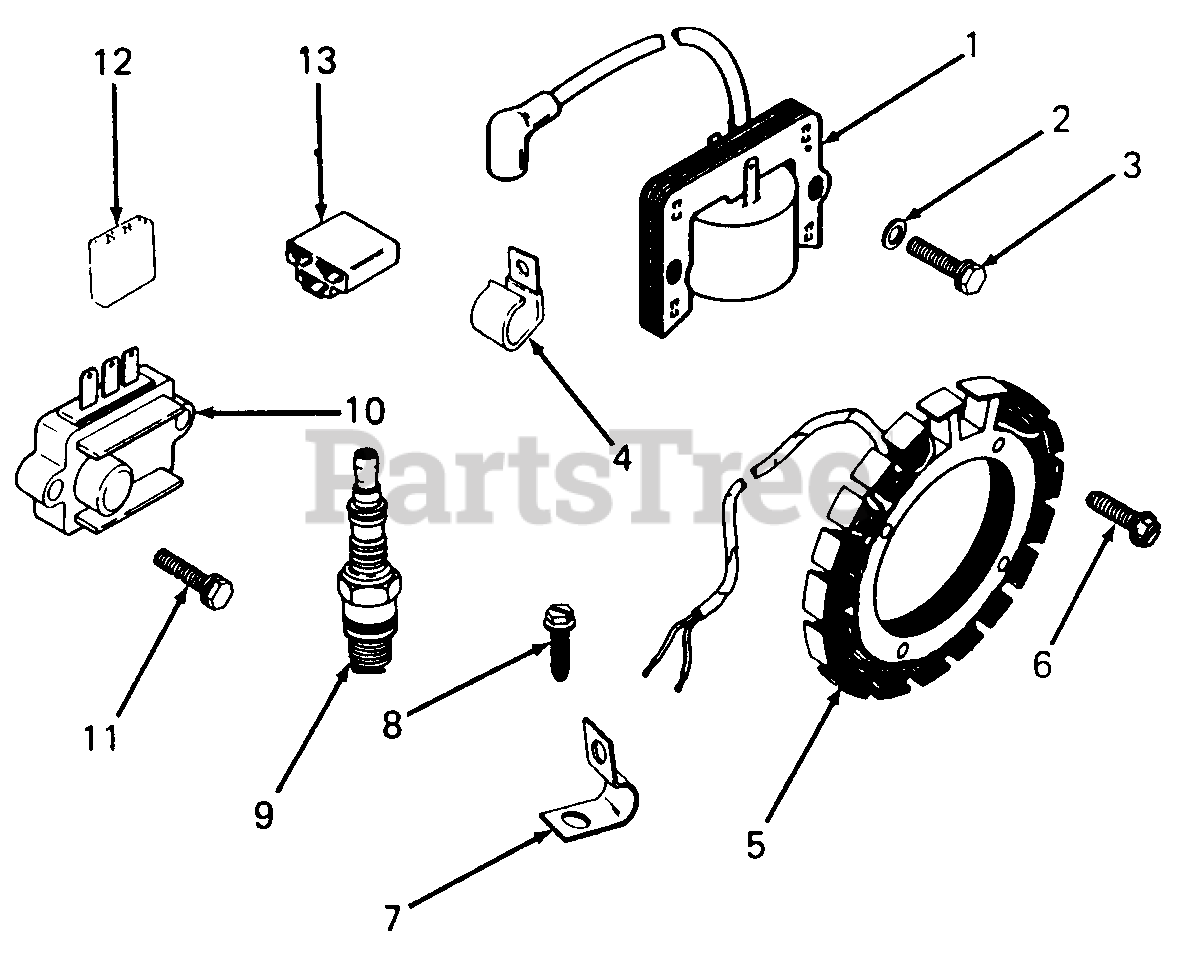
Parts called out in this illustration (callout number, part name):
1	Ignition Module
2	Washer, Plain, #10
3	Screw, HC Sems, 10-24 X 7/8 Lg
4	Clip, High Tension Lead
5	Kit, Stator
6	Screw, Hex Wash Hd, 10-24 X 3/4 Lg
8	Screw, Hex Wash Hd, 8-32 X 3/8 Lg
9	Spark Plug
10	Regulator, Rectifier
11	Screw, HC Sems, 1/4-20 X 5/8 Lg
12	Connector, Regulator
13	Connector, Lead
